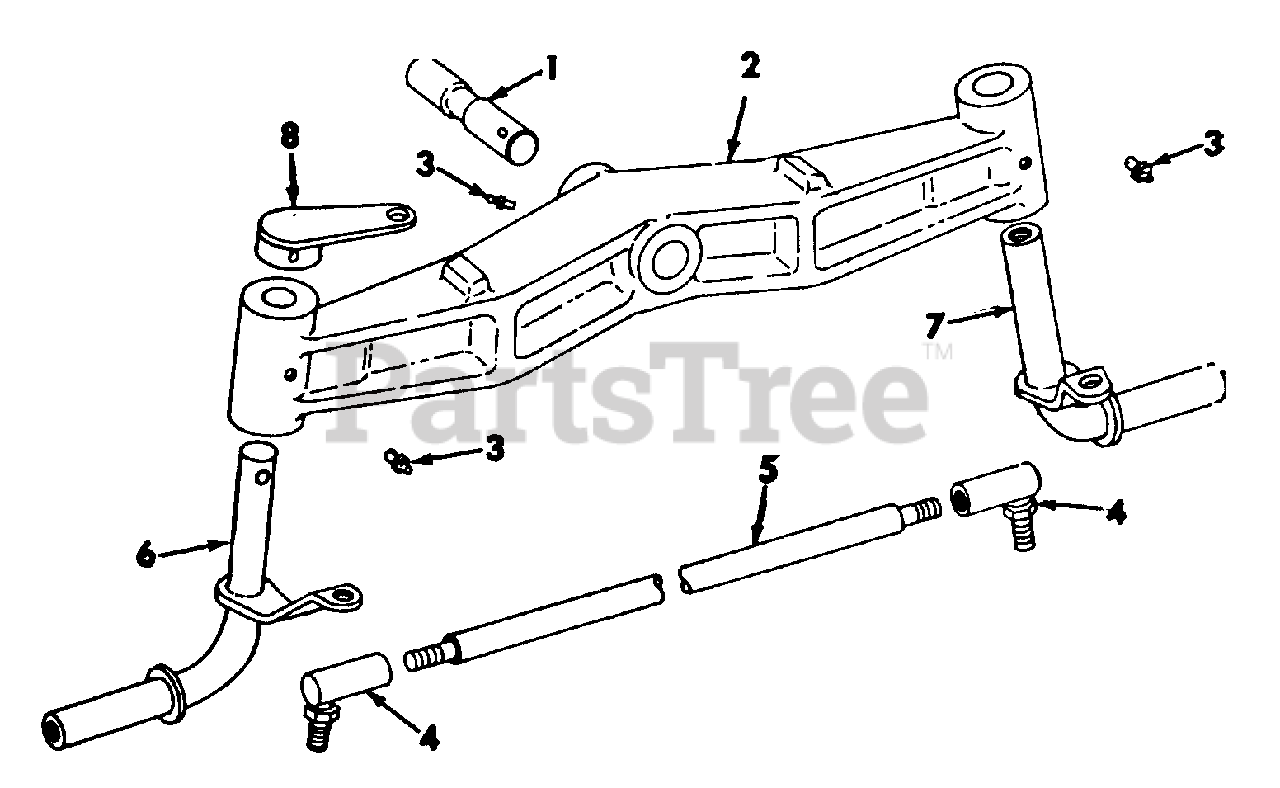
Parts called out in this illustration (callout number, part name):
1	Pin, Front Axle Pivot
2	Axle, Front
3	Fitting, 3/16 Drive Type Str Lube
4	Joint, Tie Rod
8	Arm Assy, Drag Link
